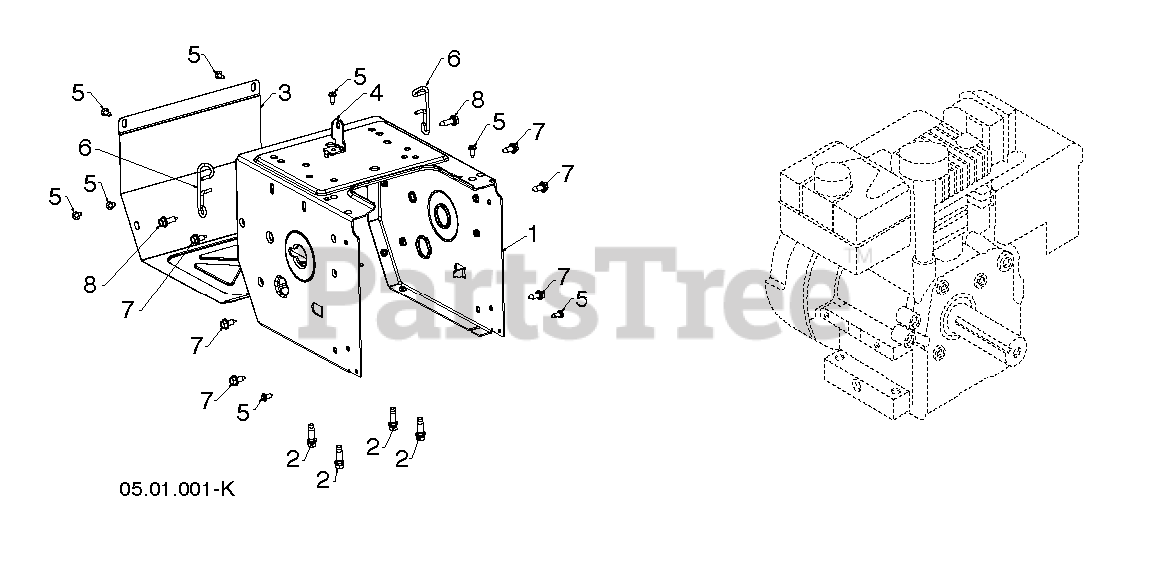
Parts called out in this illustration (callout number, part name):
1	FRAME MS 668
2	BOLT 3/8-16X1-1/8
3	COVER COVER.FRAME MS668 ORANGE
4	BRACKET.SHIFTER.BZP
5	SCREW.HEX HEAD W/COLLAR 1/4-20
6	WIREFORM.SUPPORT.CABLE
7	BOLT.HEX.HD.WASHER.5/16-18X.75
8	SCREW HEX_SERR_HD_5_16-18X1.0
